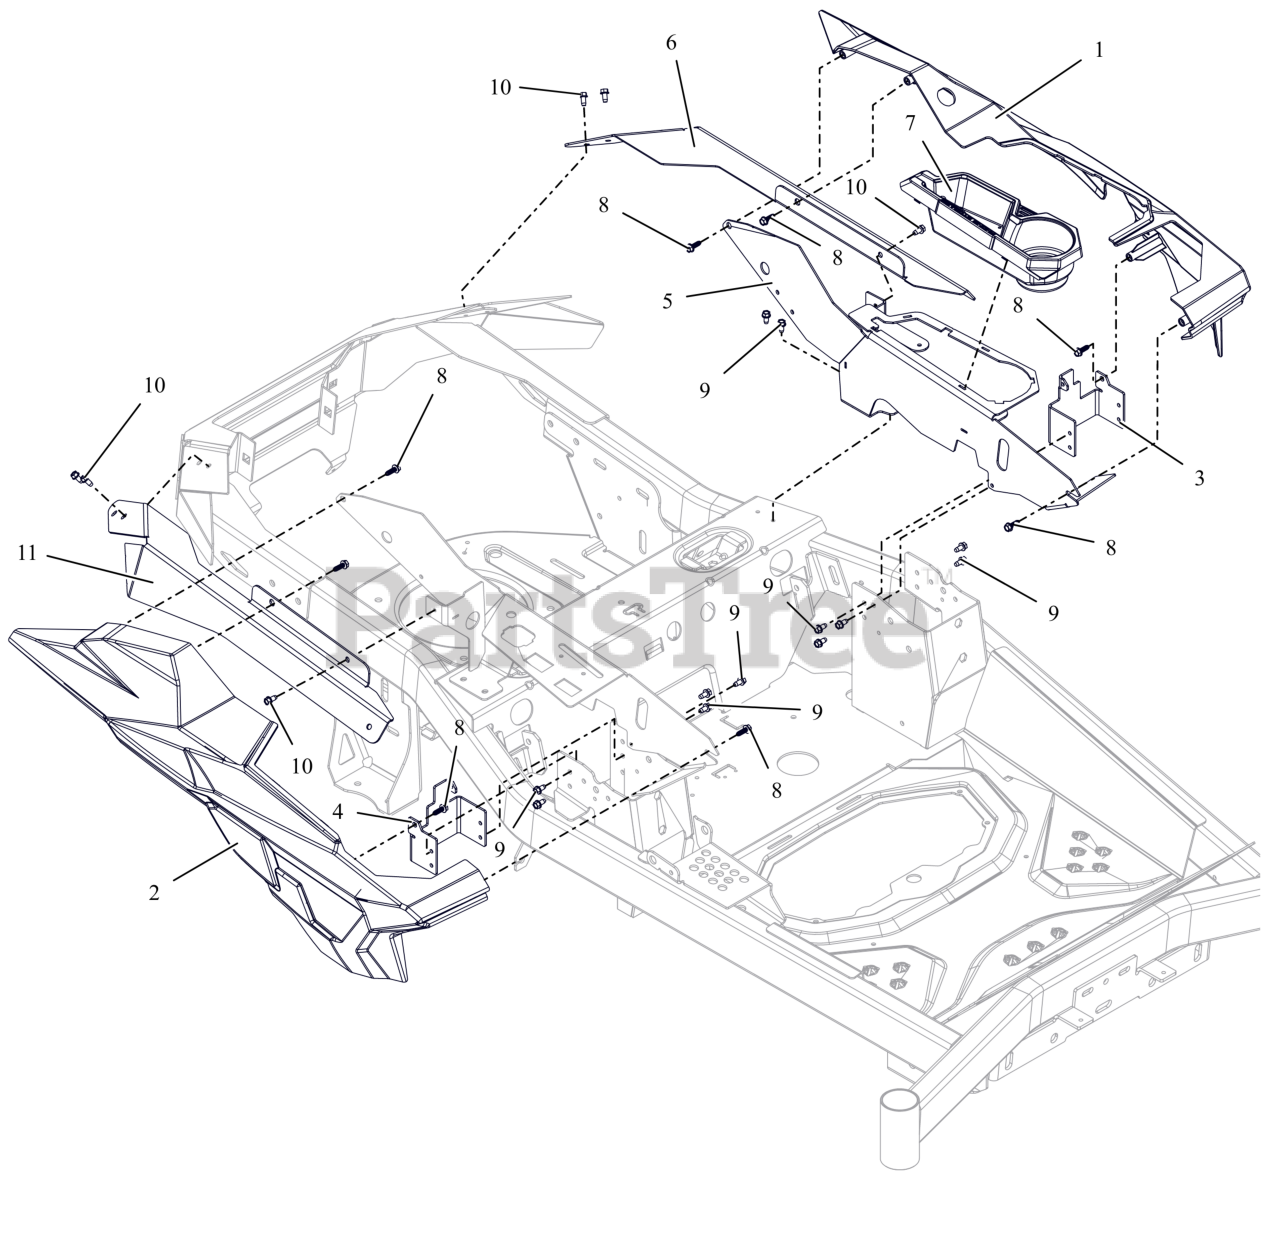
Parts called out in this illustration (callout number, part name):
1	KIT-LH GRAVELY FENDER W/ DECAL
2	FENDER- RH-GRAVELY
3	BRKT, FRONT FENDER MOUNT(LH) (BLACK)
4	BRKT, FRONT FENDER MOUNT(RH) (BLACK)
5	PANEL- CONTROL-LH-GRAVELY
6	BRKT- FENDER MOUNT-LH
7	HOLDER- CUP - GRAVELY
8	SCR, PLASTITE-HWH 0.25 X 0.75 ZC120
9	SCR-TAP .25-20X.50 HWH ZCC
10	SCR-TAP .25X.50 HWH ZB500
11	BRKT- FENDER MOUNT-RH
